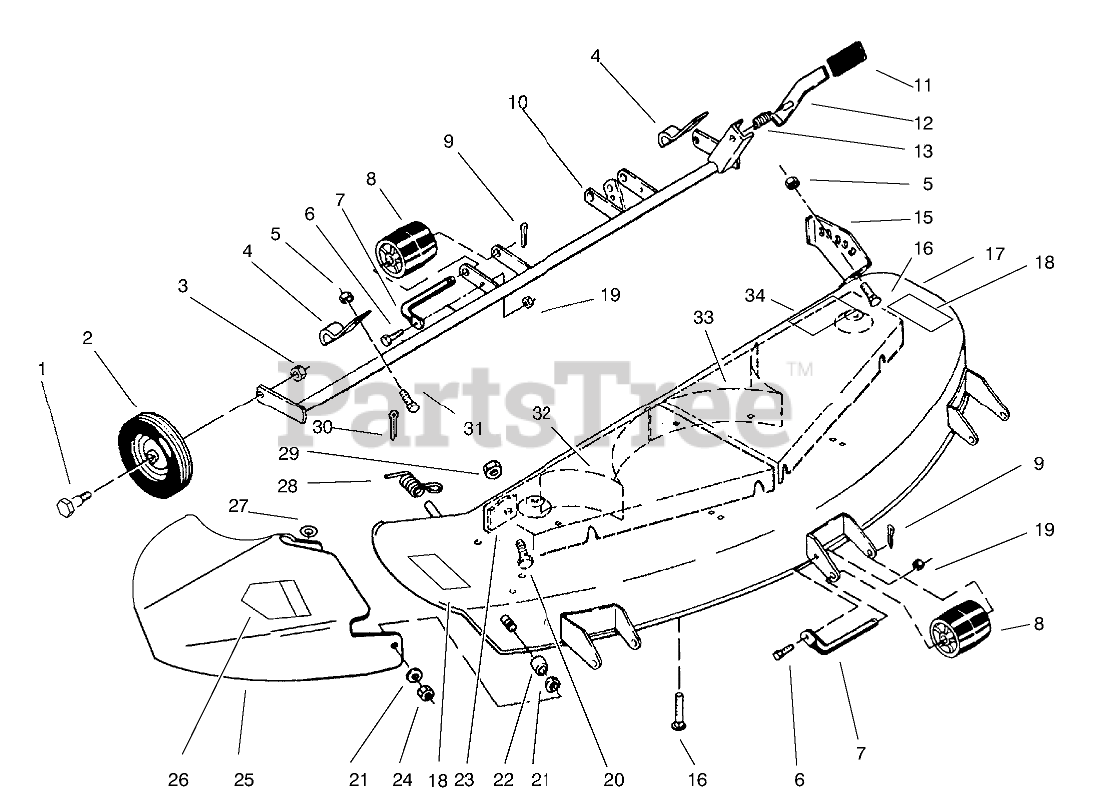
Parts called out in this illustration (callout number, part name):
1	BOLT-SHOULDER
2	WHEEL
3	NUT-HEX
4	Clamp
5	NUT-LOCK, NI
6	SCREW-HH
7	ROLLER-SHAFT
8	Roller
9	PIN-COTTER
10	Support-Gage Wheel
12	Lever
13	SPRING-COMPRESSION
15	Quadrant
16	BOLT-CARR
17	Deck-Assembly (Incl. Ref. #18, 32 & 33)
18	DECAL-DANGER
19	NUT-LOCK, NI
20	SCREW-HH
21	WASHER
22	BUSHING-PIVOT
23	GUARD-CHUTE B
24	NUT-HJ
25	Chute Assembly (Incl. Ref. #26)
26	DECAL-DANGER
27	WASHER-FLAT
28	SPRING-DEFLECTOR
29	NUT-LOCK, NI
30	PIN-COTTER
31	BOLT-CARR
32	BAFFLE-DECK RH
33	BAFFLE-DECK LH
34	DECAL-HEIGHT & BELT
